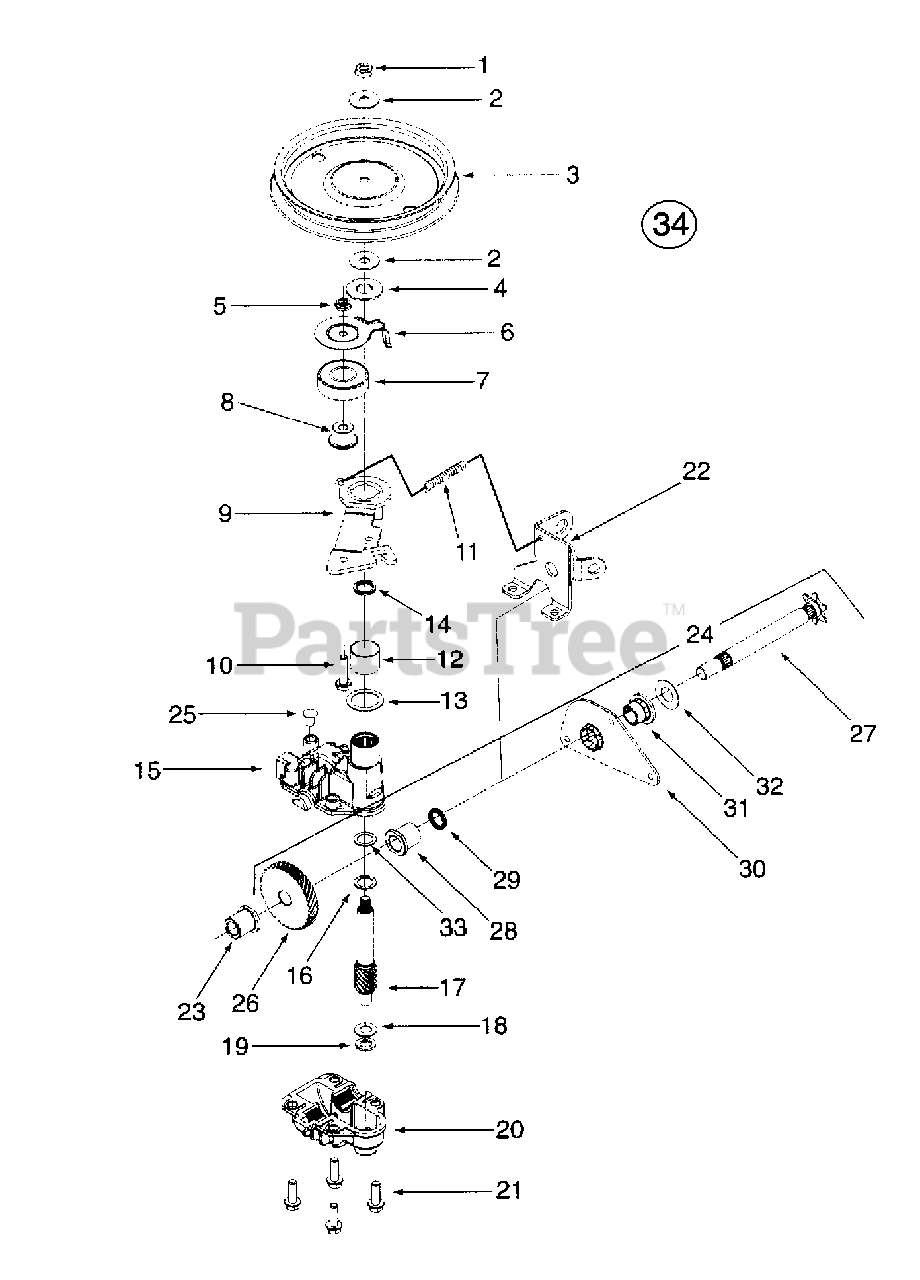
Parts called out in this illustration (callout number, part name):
1	Hx. Jam Nut 5/16-24
2	Bell Wash. .325 x .930 x .045
3	Pulley
4	Fl. Wash. .510 x 1.120 x .060
5	Hx. Jam Nut 1/4-28
6	Belt Keeper
7	Bearing
8	Flange Spacer
9	Idler Bracket Assembly
10	Hx. Cap Scr, 1/4-28 x 1.00 Gr. 5
11	Extension Spring
12	Bearing Sleeve
13	Fl. Wash. .885 x 1.145 x.030
14	Oil Seal
15	Upper Housing Assembly
16	Thrust Wash. .504 x .700 x .030
17	Pinion Shaft 10 T
18	Thr. Wash. 3/8 x .70 x .030
19	Thr. Wash. .388 x .625 x .062
20	Lower Housing Assembly
21	Hx. Scr. 1/2-20 x .75
24	Shaft Assembly
26	Gear 34 T
27	Output Shaft 6 T
28	Flange Bearing
29	Oil Seal
30	Pivot Bracket
31	Flange Bearing
32	Wash. Fl. .508 I.D. x 1.00 O.D. x .020
33	Bearing
34	Transmission Comp.
